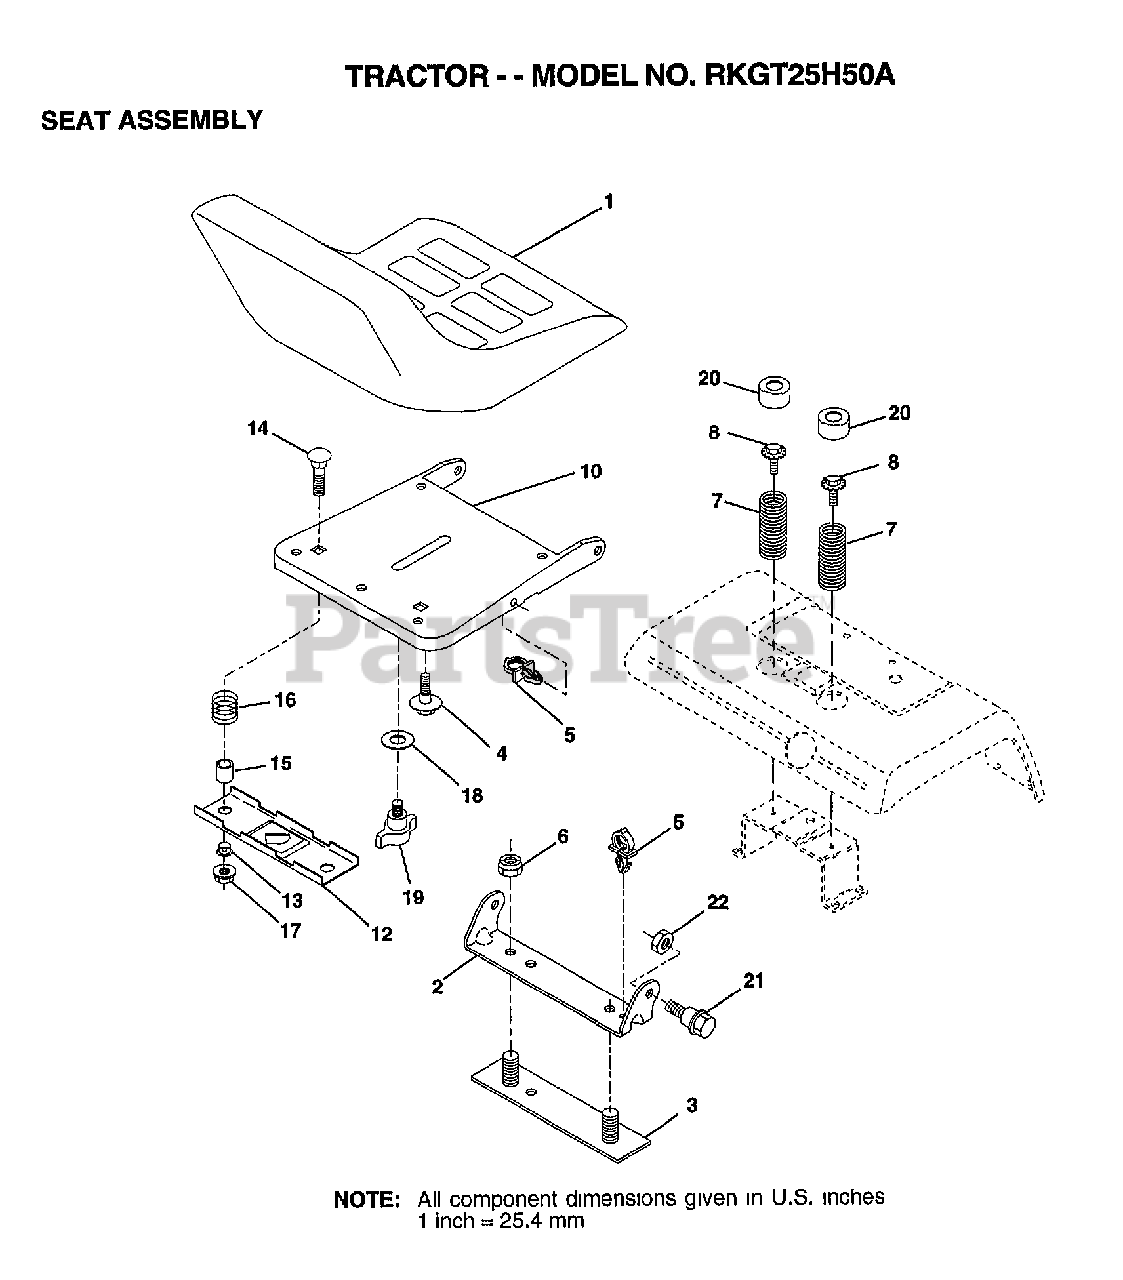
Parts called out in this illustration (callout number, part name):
2	BRACKET PVT SEAT
3	STRAP ASM FENDER
4	"BOLT,SHOULDER"
5	CLIP.PUSH-IN.HING
7	SPRING COMPRESSIO
8	BOLT.5/16-18.UNC
10	PAN-SEAT
12	BRKT SWITCH
13	BUSHING
14	BOLT-RD HD SQ NK
15	SPACER SPLIT
16	SPRING COMPRESSED
18	WASHER
19	KNOB.SEAT.ADJ.WINGNUT
20	CAP SPRING
21	"BOLT,SHOULDER"
